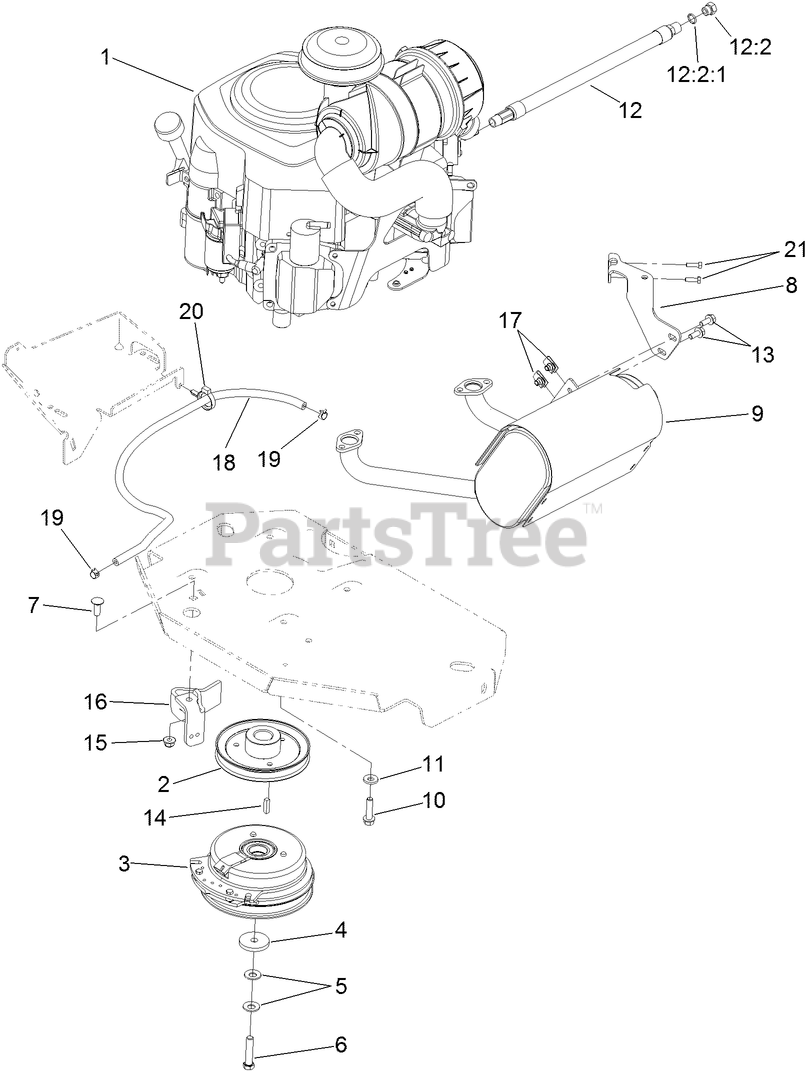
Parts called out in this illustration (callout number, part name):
2	SHEAVE
3	CLUTCH KIT
4	WASHER-CLUTCH
5	WASHER-SPRING
6	SCREW-HH W/LOCTITE
7	SCREW-CARR
8	MUFFLER BRACKET KIT
9	MUFFLER
10	SCREW-HWH
11	WASHER-BELLEVILLE
12	OIL DRAIN HOSE ASM
12:2	PLUG-HH
12:2:1	O-RING
13	SCREW-HHF
15	NUT-HF, NI
16	CLUTCH-ANCHOR
17	NUT-U
18	HOSE-FUEL
19	CLAMP-HOSE
20	CLAMP-HOSE
21	SCREW-HH
